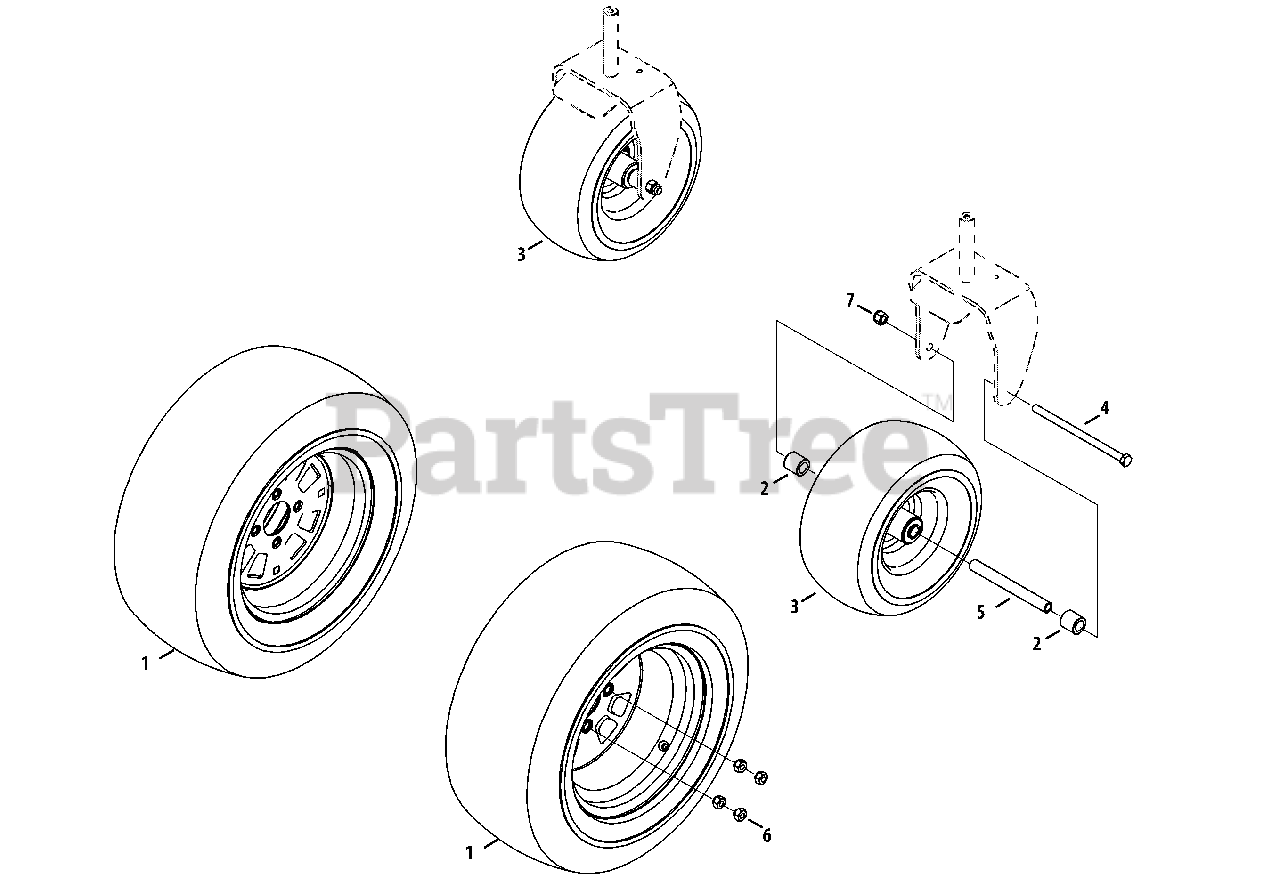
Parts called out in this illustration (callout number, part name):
1	Wheel Assy., 22 x 9.5 x 12
2	Hub, .76 x 1.23 x 1.25
3	Complete Wheel Assy., 13 x 6.5-6
4	Hex Screw, 1/2-13 x 8.5
5	Spacer, .51 x .75 x 1.25
6	Lug Nut, 7/16-14
7	Hex Lock Nut, 1/2-13
